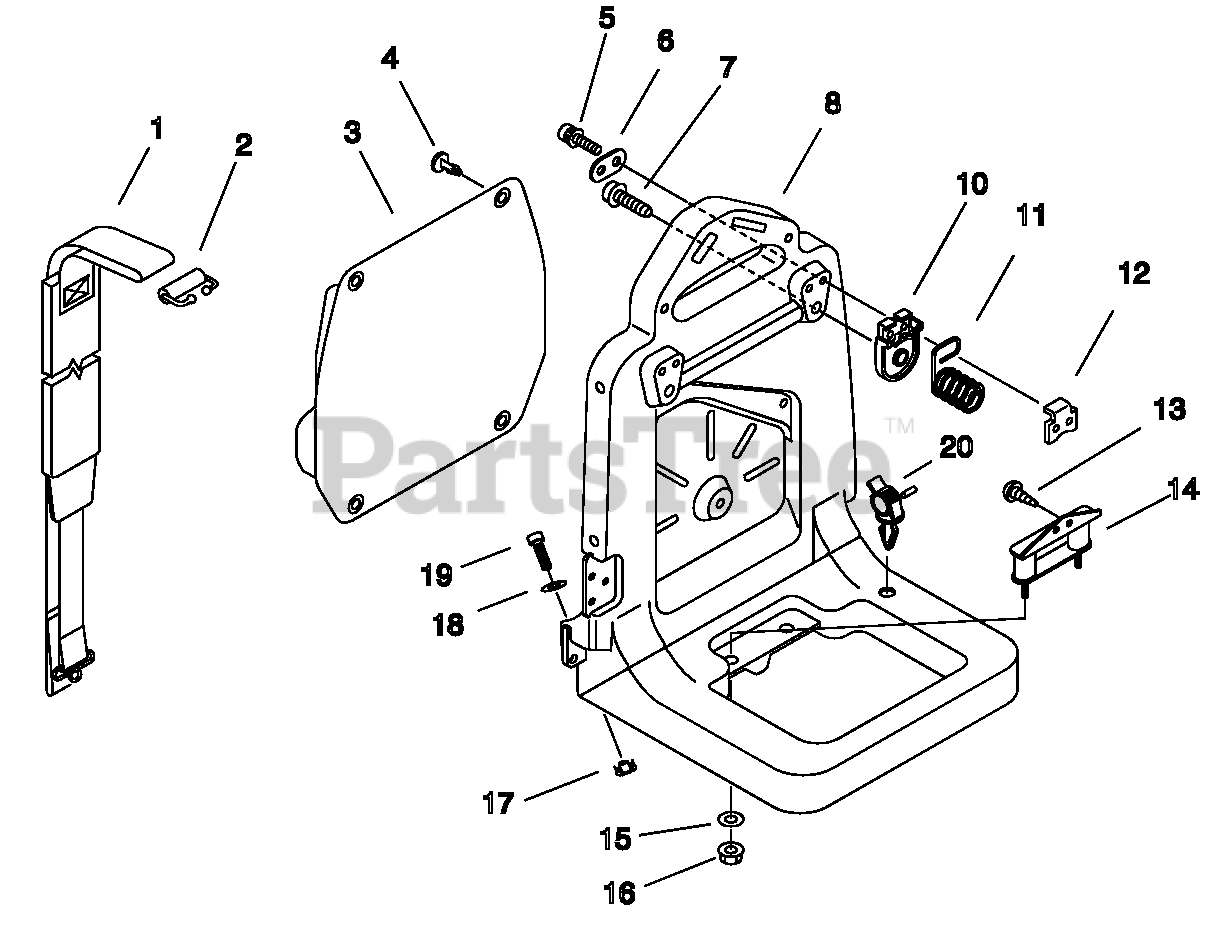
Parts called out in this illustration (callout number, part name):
1	HARNESS ASSY
1	HARNESS ASSY, BACKPACK
2	CLIP, HARNESS
3	CUSHION, BACKPACK
5	BOLT 5×20
6	PLATE, EYE
7	BOLT 5×20
8	WASHER 5.5×16×2T
9	FRAME, BACKPACK
10	HOLDER, SPRING
11	SPRING, COMPRESSION
12	PLATE, THREADED
13	SCREW TAPPING 5×16
14	CUSHION 5
15	WASHER 5
16	NUT, FLANGE M5
18	WASHER 6.6×20×1.6
19	BOLT 6×25
20	CLIP, CABLE
